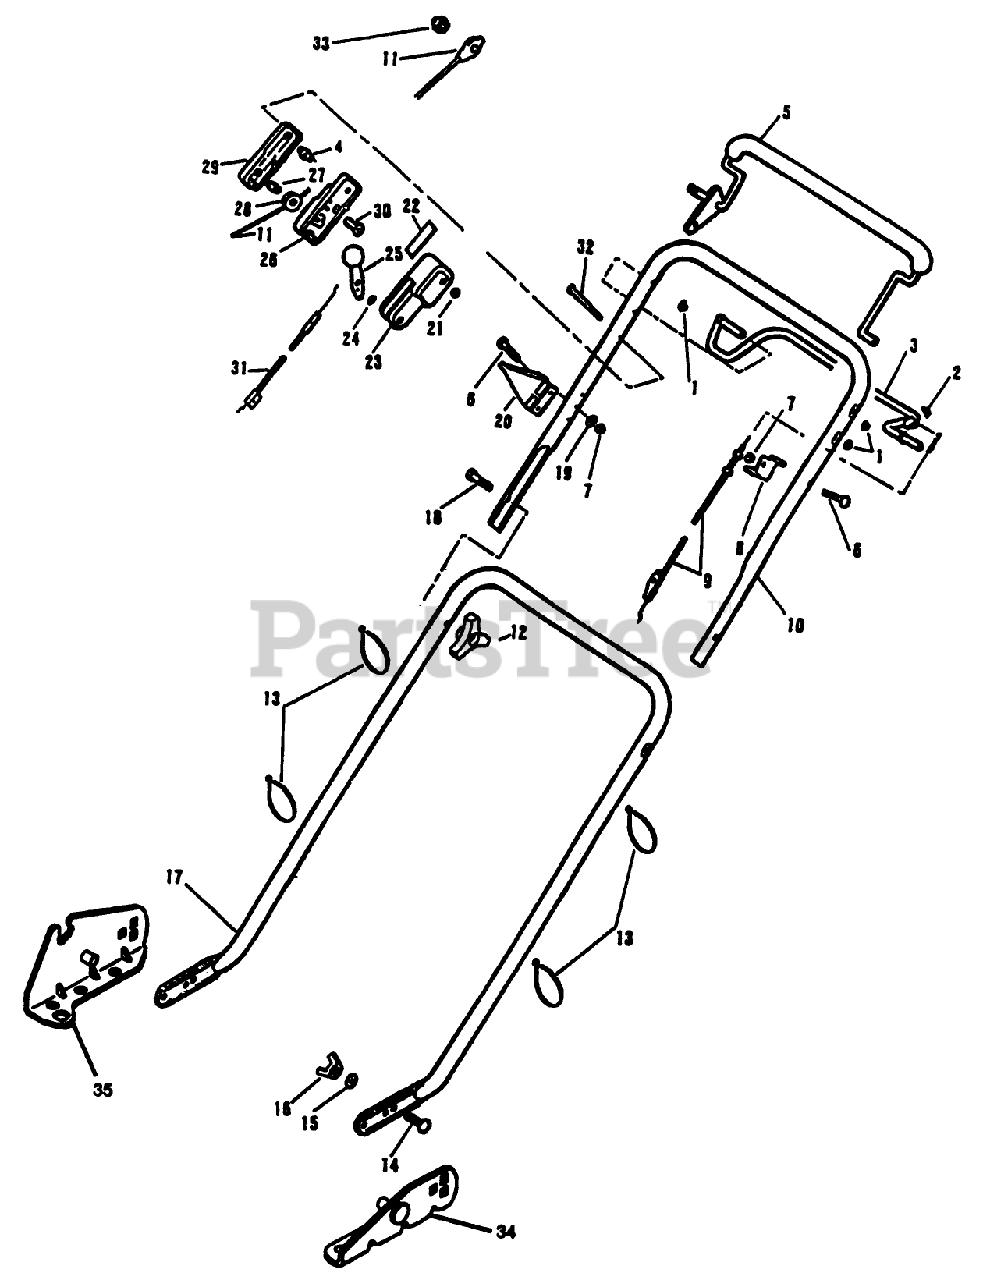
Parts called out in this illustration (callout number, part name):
4	COLUMN
5	CONTROL LEVER ARG
7	LOCKNUT E
8	ANCHOR C'DUIT TRO
9	CABLE - CONTROL
11	CONTROL CABLE
13	TIE-CABLE
16	NUT WING
17	HANDLE-LOWER(GREEN *
19	WASHER
21	NUT C/LOCK E
24	WASHER-SPRING
25	LEVER&KNOB AY WES
27	PIN SKF
28	PULLEY PL
29	OUTER CONTROL CASE
30	SCREW
31	CABLE TH'TTLE WES
32	SCREW
33	NUT ACORN
34	HANDLE BRKT & PIN
